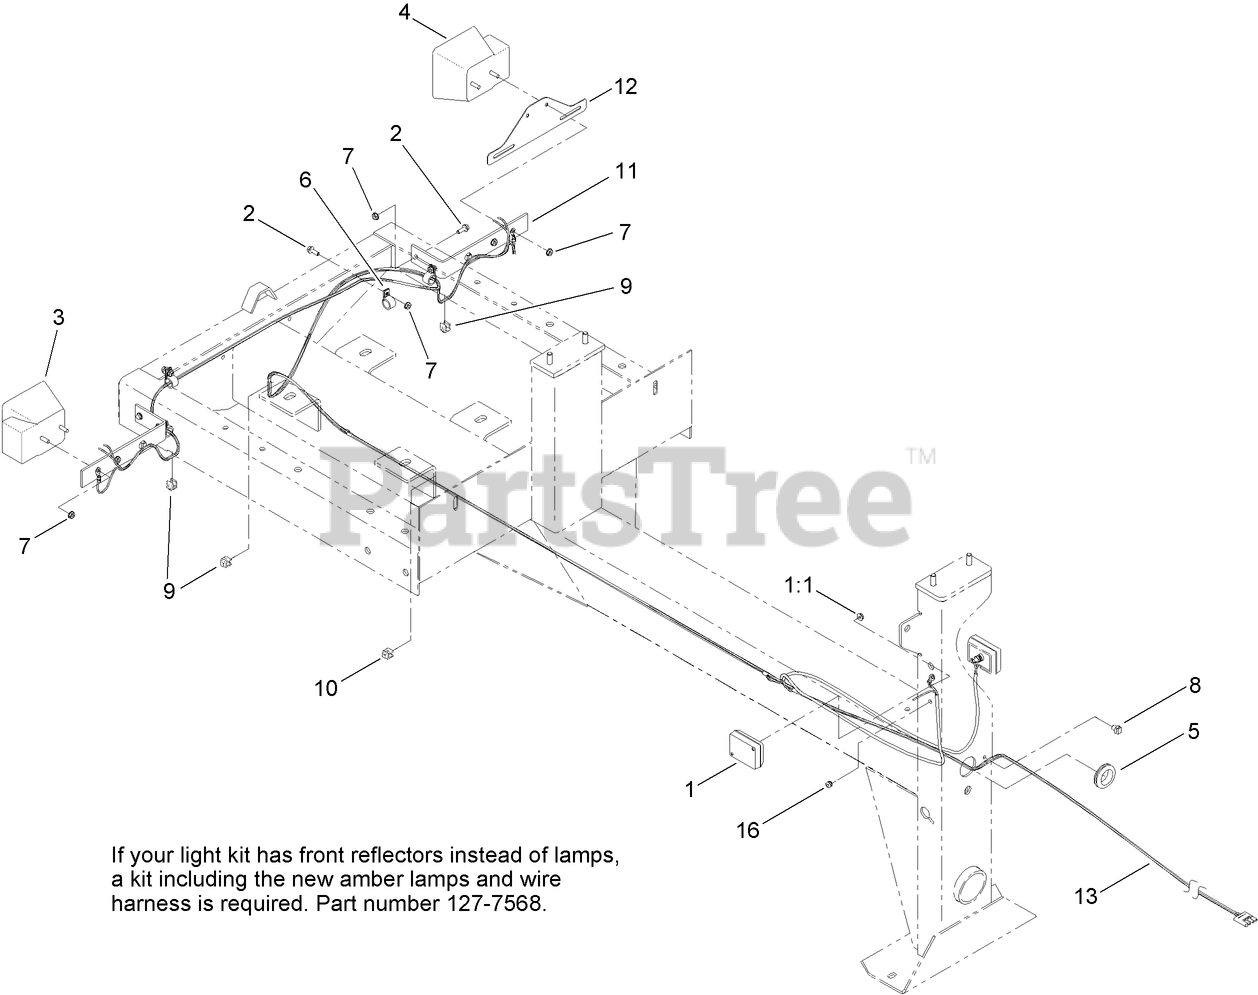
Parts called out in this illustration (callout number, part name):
1	LAMP-MARKER, FRONT SIDE
1:1	NUT-KEPS
2	SCREW-HHF
3	LIGHT-TAIL, RH
4	LIGHT-TAIL, LH
5	GROMMET
6	CLAMP-CABLE
7	NUT-KEPS
8	CLIP-TIE
9	CLIP-EDGE
10	CLIP-EDGE W/TIE, PERPENDICULAR
11	BRACKET-UNIVERSAL
12	HOLDER-PLATE, LICENSE
13	HARNESS-WIRE
16	GROMMET
